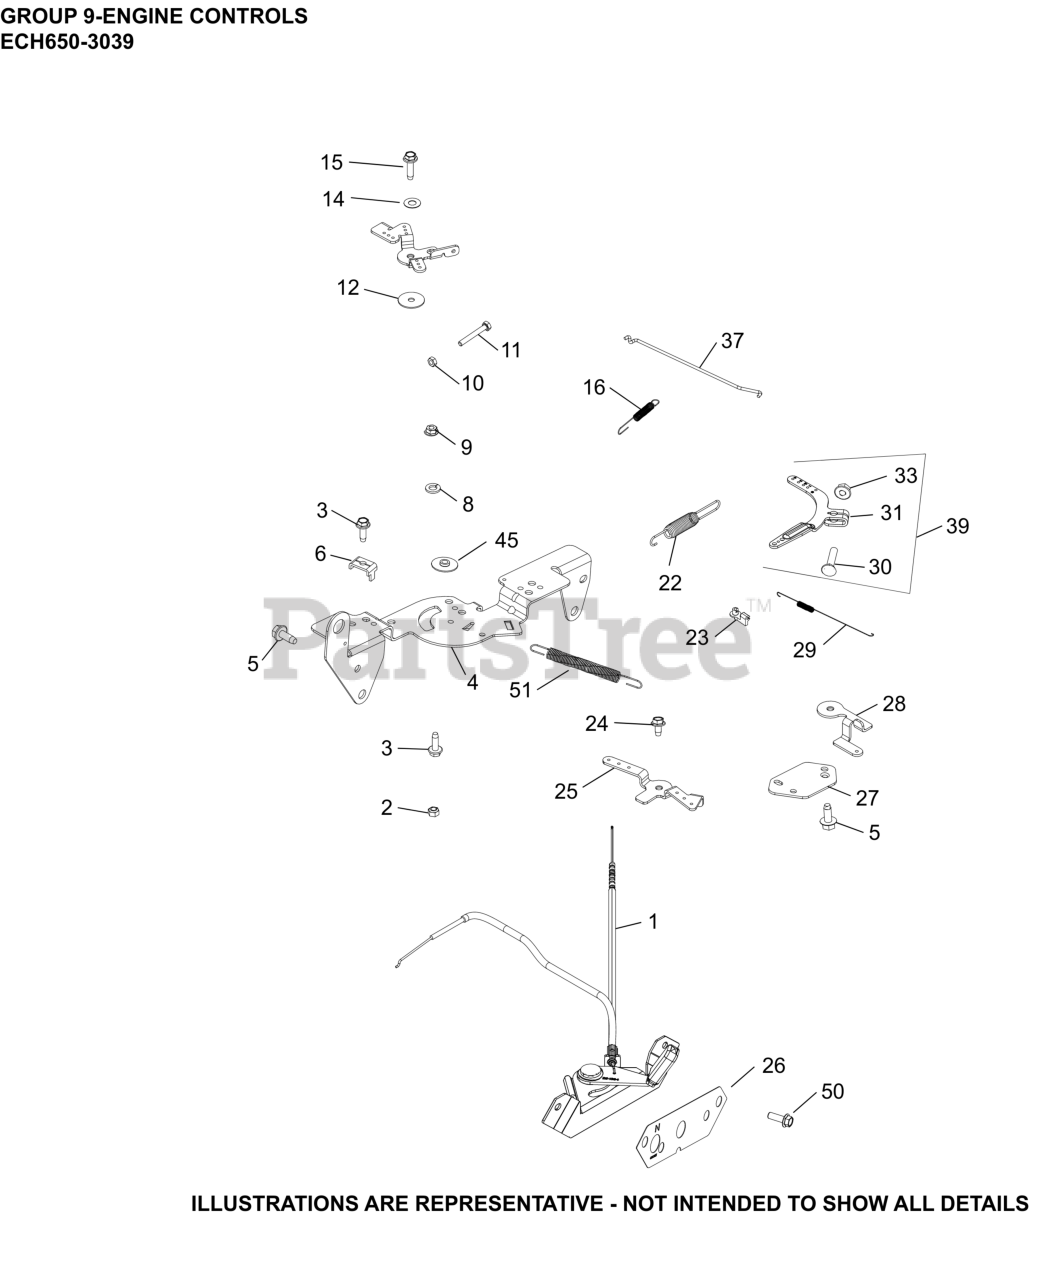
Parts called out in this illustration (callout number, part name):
1	CABLE, CONTROL ASSEMBLY
2	NUT, LOCK M5X.8
3	SCREW, THREAD FORMING
4	BRACKET, CONTROL
5	SCREW, THREAD FORMING
6	CLAMP, CABLE CABLE
8	WASHER, SPRING LOCK 1/4"
9	NUT, FLG M5X.8
10	NUT, M4X0.7
11	SCREW, CAP M4X.7X30
12	WASHER, FLAT 5.5 MM
14	WASHER, SPRING 1/4"
15	SCREW, THD FRM-USE 25 086 473-S
16	SPRING, THROTTLE LIMITER
22	SPRING, GOVERNOR (ORANGE)
23	BUSHING, THROTTLE LINKAGE
24	SCREW, THREAD FORMING
25	LEVER, THROTTLE CONTROL
26	LABEL, CONTROL PANEL
27	BRACKET, CABLE SUPPORT
28	LEVER, THROTTLE ACTUATOR
29	SPRING, LINKAGE
30	BOLT, RD HD SQ NECK M6X1.0X25
31	LEVER, GOVERNOR - (#2409069S)
33	NUT, FLG M6X1.0
37	LINKAGE, THROTTLE
39	LEVER, GOVERNOR ASSEMBLY
NI	SCREW, HI-LOW
